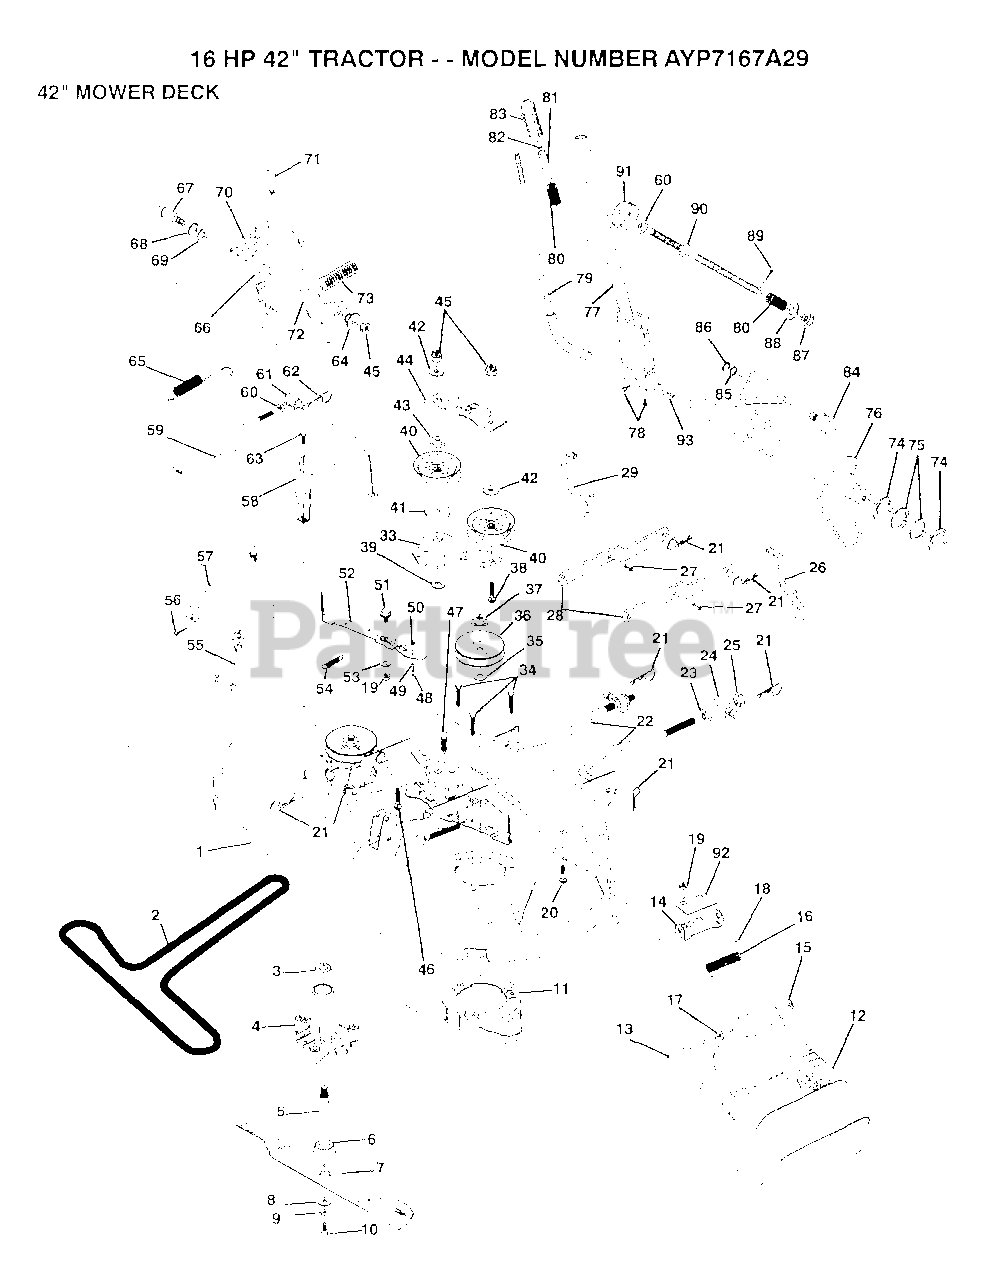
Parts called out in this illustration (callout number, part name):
2	BELT-V.92.4.MWR
3	BEARING
4	HSG ASM MANDREL
6	BEARING.BALL
8	WASHER BLADE
10	BLADE BOLT
12	DEFLECTOR.SHIELD
13	HINGE ROD
14	DEFLECTOR BRKT
15	NUT PUSH M
16	SPRING TORSION
17	WASHER
18	CAP-SLEEVE LT
20	BOLT
22	LINK.FRONT
23	NUT
24	TRUNION
25	NUT.LK.W/WSH.1/2.
26	LINK LIFT RH
27	SPRING PIN
29	LIFT LINK LH
30	NUT
33	IDLER ARM
35	WASHER
38	BOLT
39	HARDENED WASHER
40	FLAT IDLER PULLEY
41	SPACER RETAINER
42	WASHER GT
43	RETAINER SPACER
44	IDLER ARM STIFF
46	BOLT CARRIAGE
47	XMAS TREE FASTNER
48	SHOULDER BOLT
50	LOCKNUT
52	BRAKE PAD ARM ASM
53	HARD SMALL WASHER
54	SPRING EXTENSION
55	PIVOT ROD
57	CLUTCH ROD SECOND
60	NUT
61	TRUNION
62	RETAINER M
63	SCREW LT
64	BUSHING
65	RETURN SPRING
66	CLUTCH ARM SECOND
67	SHOULDER BOLT
68	RING
69	WASHER
70	SPRING KEEPER
75	WASHER
76	LIFT SHAFT ASM
77	PIN-GROOVE LT
78	NYLON BEARING
83	GRIP
85	WASHER
86	KLIP RING
87	NUT T
88	WASHER
90	ROD LIFT LT
92	STIFFENER BRKT
94	TRUNION LT
